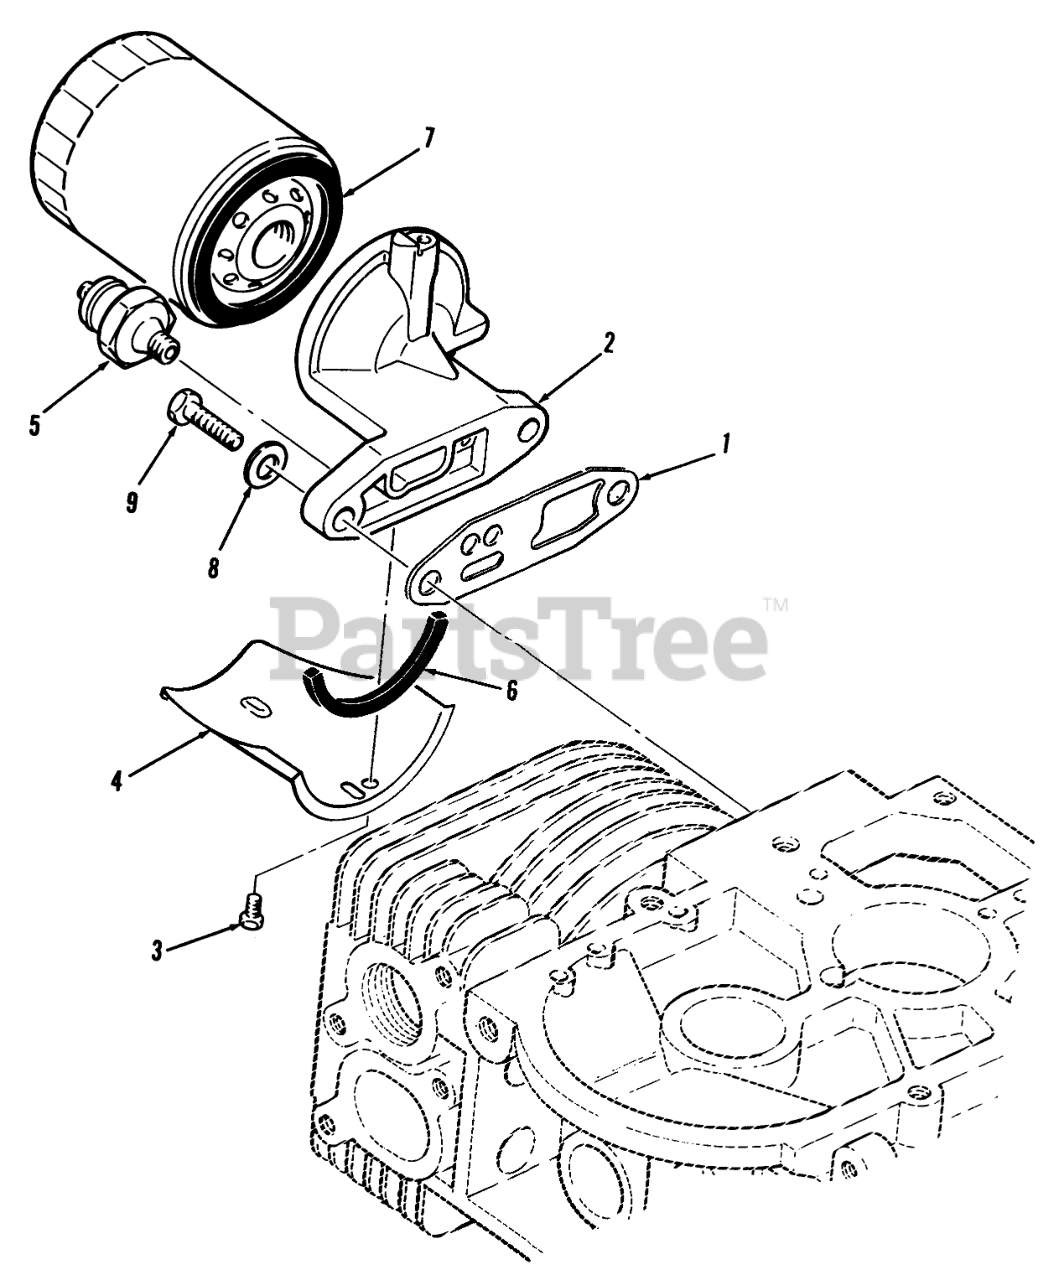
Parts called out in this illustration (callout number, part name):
1	GASKET
2	Adapter
3	Bolt
4	OIL-DRAIN
5	OIL-PRESSURE SWITCH
6	OIL-DRAIN SEAL
7	OIL FILTER
8	Washer
9	HHCS 5/16-18 X 1
